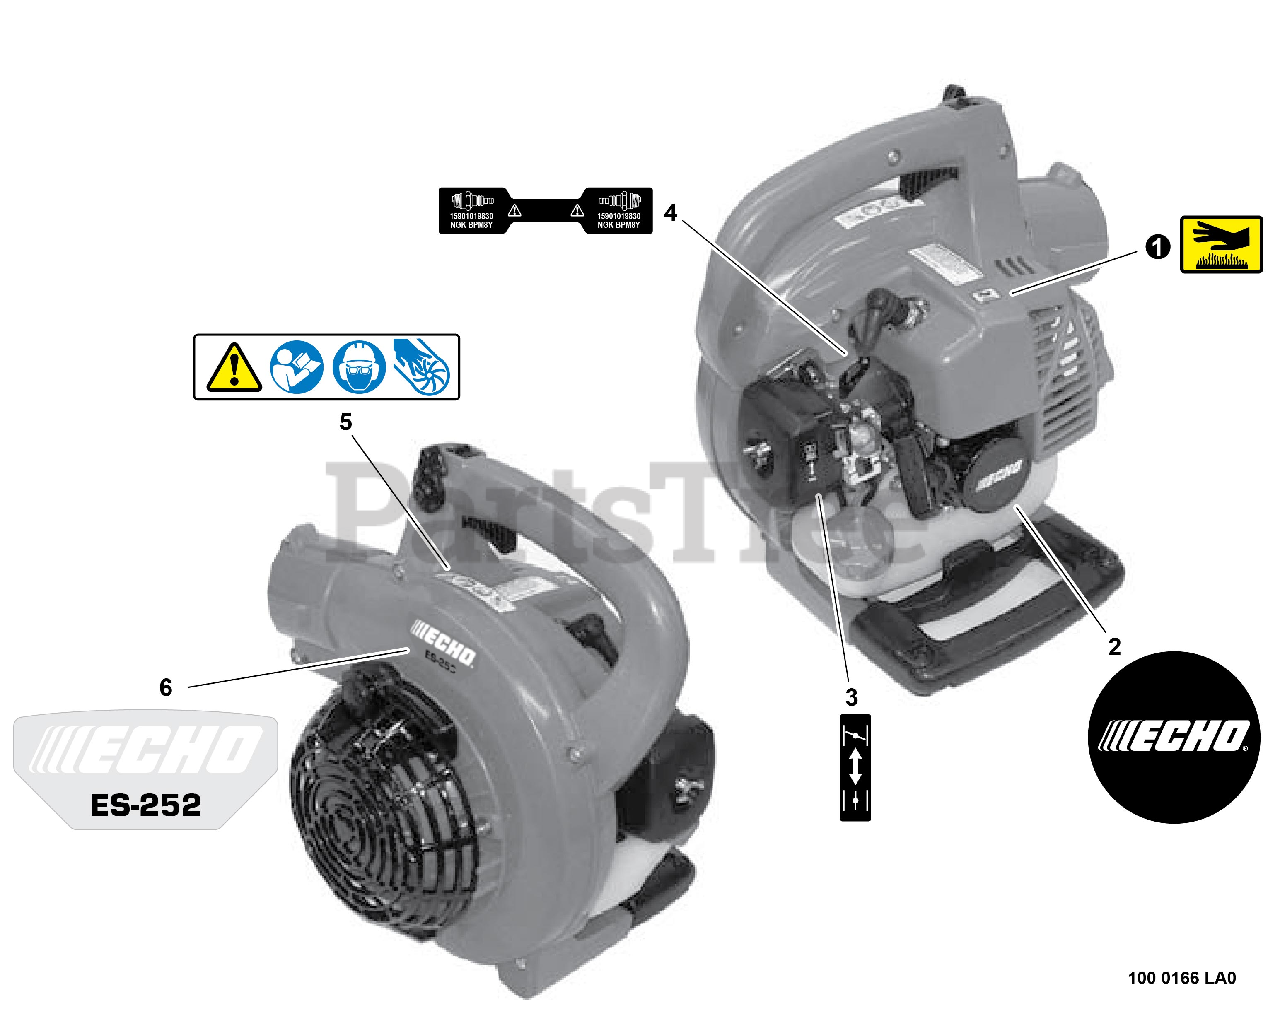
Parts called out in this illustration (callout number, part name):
1	LABEL - HOT SURFACE
2	LABEL - ECHO
3	LABEL - CHOKE
4	LABEL - SPARK PLUG -- BPM-8Y
5	LABEL - CAUTION
6	LABEL - MODEL ES-252
